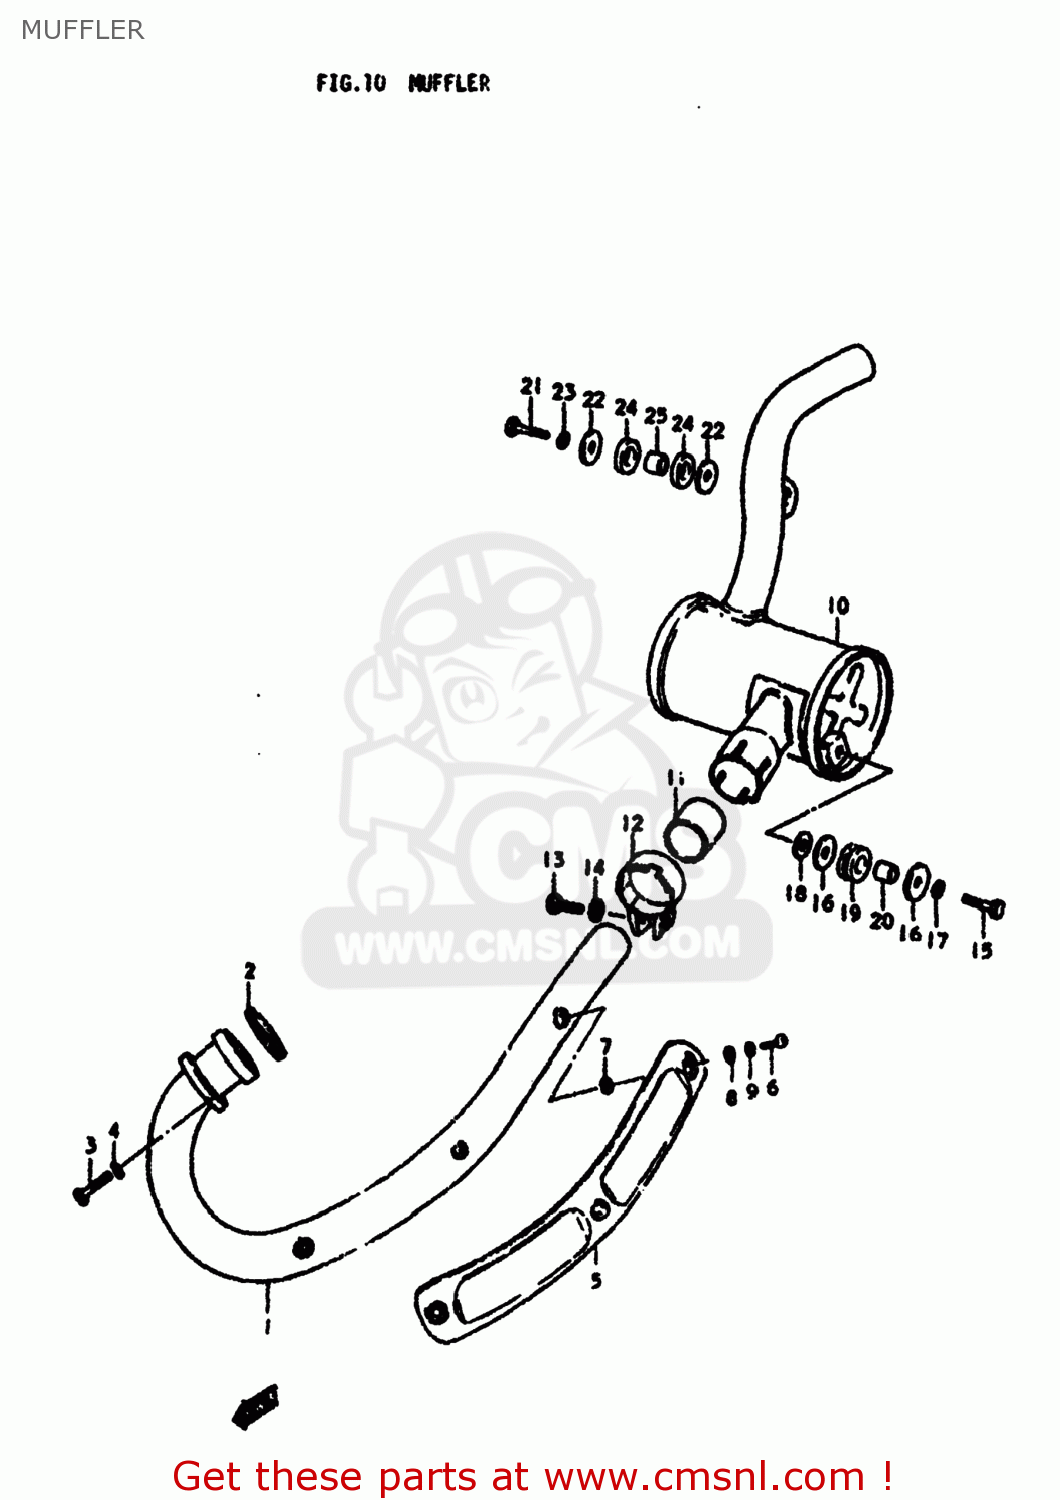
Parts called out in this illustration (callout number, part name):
1	PIPE,EXHAUST
2	GASKET,EXHAUST PIPE (NAS)
3	BOLT
4	LOCK WASHER
5	COVER,EXHAUST PIPE
6	SCREW
7	GASKET 6.2X12X1.5 (MCA)
8	WASHER
9	LOCK WASHER
10	BODY,MUFFLER
11	CONNECTOR,MUFFLER
12	CLAMP,MUFFLER CONNECTOR
13	BOLT 8X35
14	WASHER
15	BOLT (8X30)
16	WASHER (8.5X29X1.6)
17	LOCK WASHER
18	GASKET
19	CUSHION
20	SPACER (8.6X13.8X13)
21	BOLT(8X27)
22	WASHER (8.5X29X1.6)
23	LOCK WASHER
24	CUSHION
25	SPACER (8.6X13.8X13)
